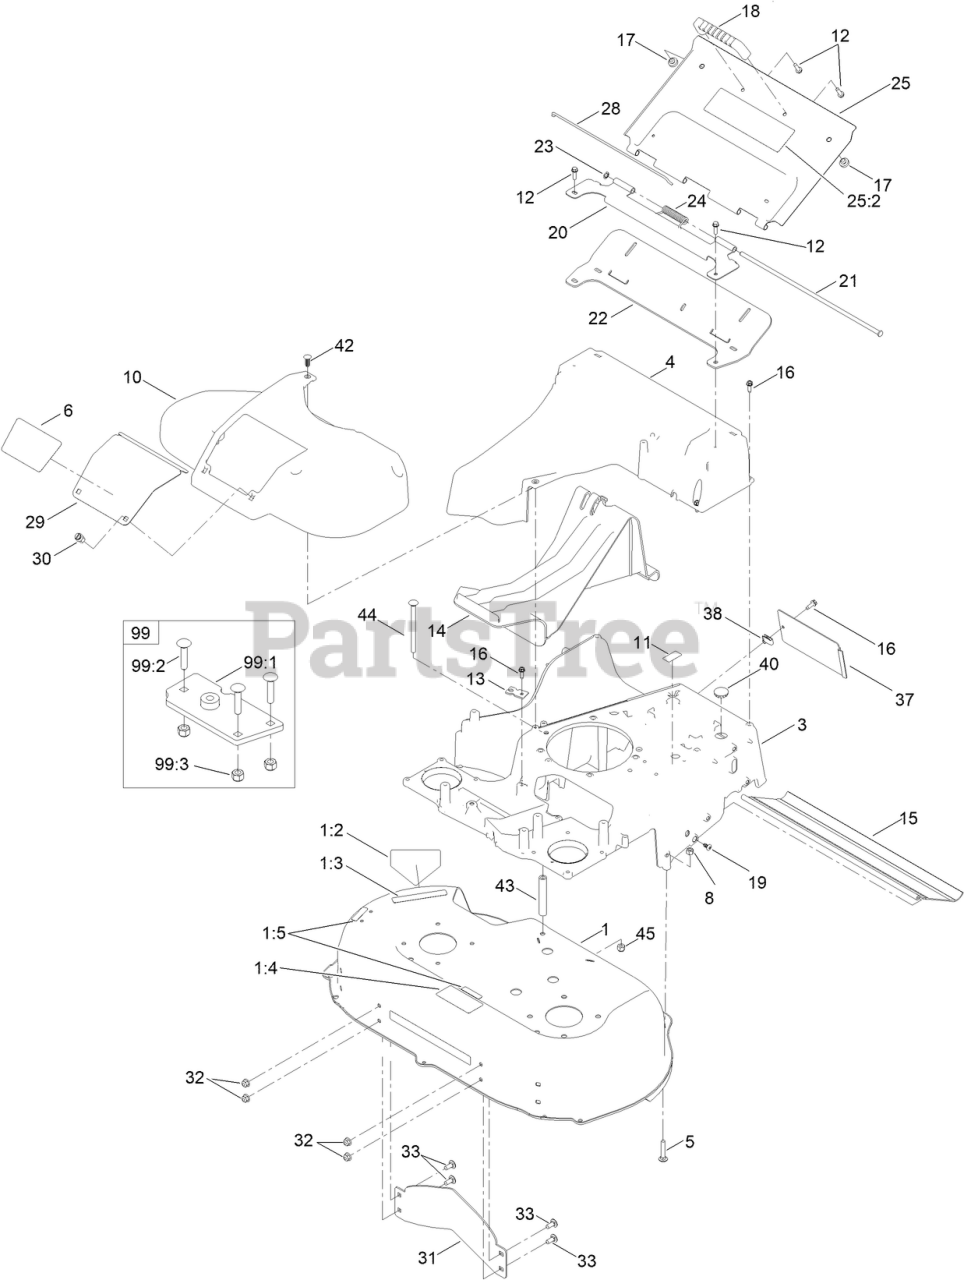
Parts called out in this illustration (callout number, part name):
1	DECK ASM
1:2	DECAL-DANGER
1:3	DECAL-DANGER
1:5	DECAL-WARNING
3	FRAME-30
5	BOLT-CAR
6	DECAL-30 INCH
8	NUT-LOCK, NI
10	COVER-BELT
11	DECAL-PATENT
12	SCREW-HWH
13	BRACKET-CABLE, TRACTION
14	PLUG-MULCH
15	SHIELD-TRAILING
16	SCREW-HWHTF
17	BUMPER
18	HANDLE-DOOR
19	SCREW-PTH
20	BRACKET-HINGE
21	PIN-HINGE
22	SEAL-DOOR
23	RING-RETAINING
24	SPRING-TORSION, COVER
25	REAR DOOR ASM
25:2	DECAL-WARNING
28	CLIP-SEAL
29	DOOR-ACCESS
30	FASTENER
31	BAFFLE-CONTROL
32	NUT-HF, NI
33	SCREW-CARR
37	COVER-FRAME
40	PLUG-BUTTON
42	CLIP-XMAS TREE
43	SPACER
44	BOLT-CARR
45	NUT-HEX
99	FRAME PLATE KIT
99:1	PLATE-FRAME
99:2	SCREW-CARR
99:3	NUT-LOCK, NI
